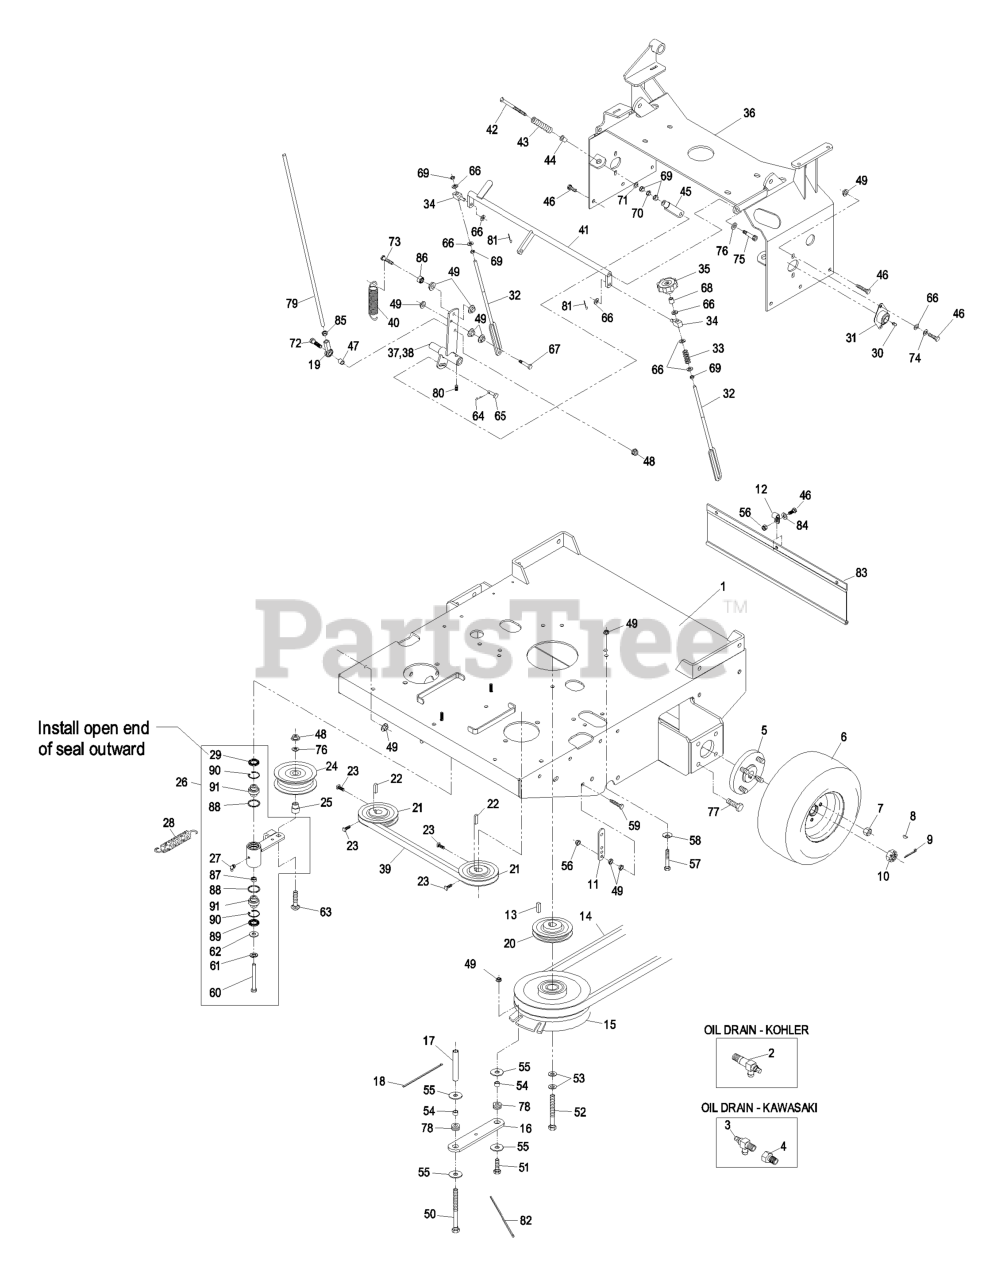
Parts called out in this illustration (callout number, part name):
1	Eng Deck 103-2963-01 W/ Decals
2	VALVE-DRAIN, OIL
3	VALVE-DRAIN, OIL
4	ADAPTER
6	ASM, DRIVE TIRE
7	NUT-LUG
8	KEY-WOODRUFF
9	PIN-COTTER
10	NUT-HEX, SLOTTED
11	TAB-SPRING, EXTENSION
12	CLIP-LOOM
14	BELT,B 83.65
15	CLUTCH ASM
16	STRAP-CLUTCH, BRAKE
17	SPACER,SHIELD
18	TIE-CABLE
19	JOINT-BALL END, LH
20	PULLEY
21	SHEAVE ASM
23	SCREW-SET
25	BUSHING-IDLER
26	Kit, Idler Arm W/Bearings
27	FITTING-GREASE, 90 DEG
28	SPRING-EXTENSION
29	SEAL-LIP, SINGLE
30	FITTING-GREASE
31	BEARING-FLANGE, SIDE
32	LINK,SPEED CONTROL
33	SPRING-COMPRESSION
35	KNOB-TRACKING
37	WLD,LH CONTROL ARM
40	SPRING-EXTENSION
41	WLD,CRANK SPEED CNTRL
42	BOLT-RETURN, NEUTRAL
43	SPRING,COMPRESSION (NEUT)
44	BUSHING-FLANGED
45	YOKE-ADJUSTABLE
46	SCREW-HH
47	TUBE,PUMP LINK SPACER
48	NUT-HHF, WHIZ
50	SCREW-HH
51	SCREW-HH
52	SCREW-HH
53	WASHER-SPRING
56	NUT-LOCK, NI
57	SCREW-HH
58	WASHER-SPRING
59	BOLT-TAP, HH
60	SCREW-HH
61	WASHER-LOCK
62	WASHER-FLAT
63	SCREW-CARR
64	PIN-COTTER
65	PIN-CLEVIS
66	WASHER-PLAIN
67	SCREW-HH
69	NUT-HEX
70	NUT-JAM
71	WASHER-FLAT
72	SCREW-HH
73	SCREW-HH
74	WASHER-LOCK
75	SCREW-HSH
76	WASHER-FLAT
77	SCREW-HHF
78	GROMMET
79	LINK,DRIVE (PLTD)
80	SCREW-SET
81	PIN-COTTER
82	TIE-PLASTIC
83	SHIELD,DRAG
84	WASHER-FLAT
85	NUT-HEX JAM, LH
86	Nut, Jam 5/16-18
89	SEAL-LIP, DOUBLE
90	RING-SNAP
91	BEARING-SPHERICAL
